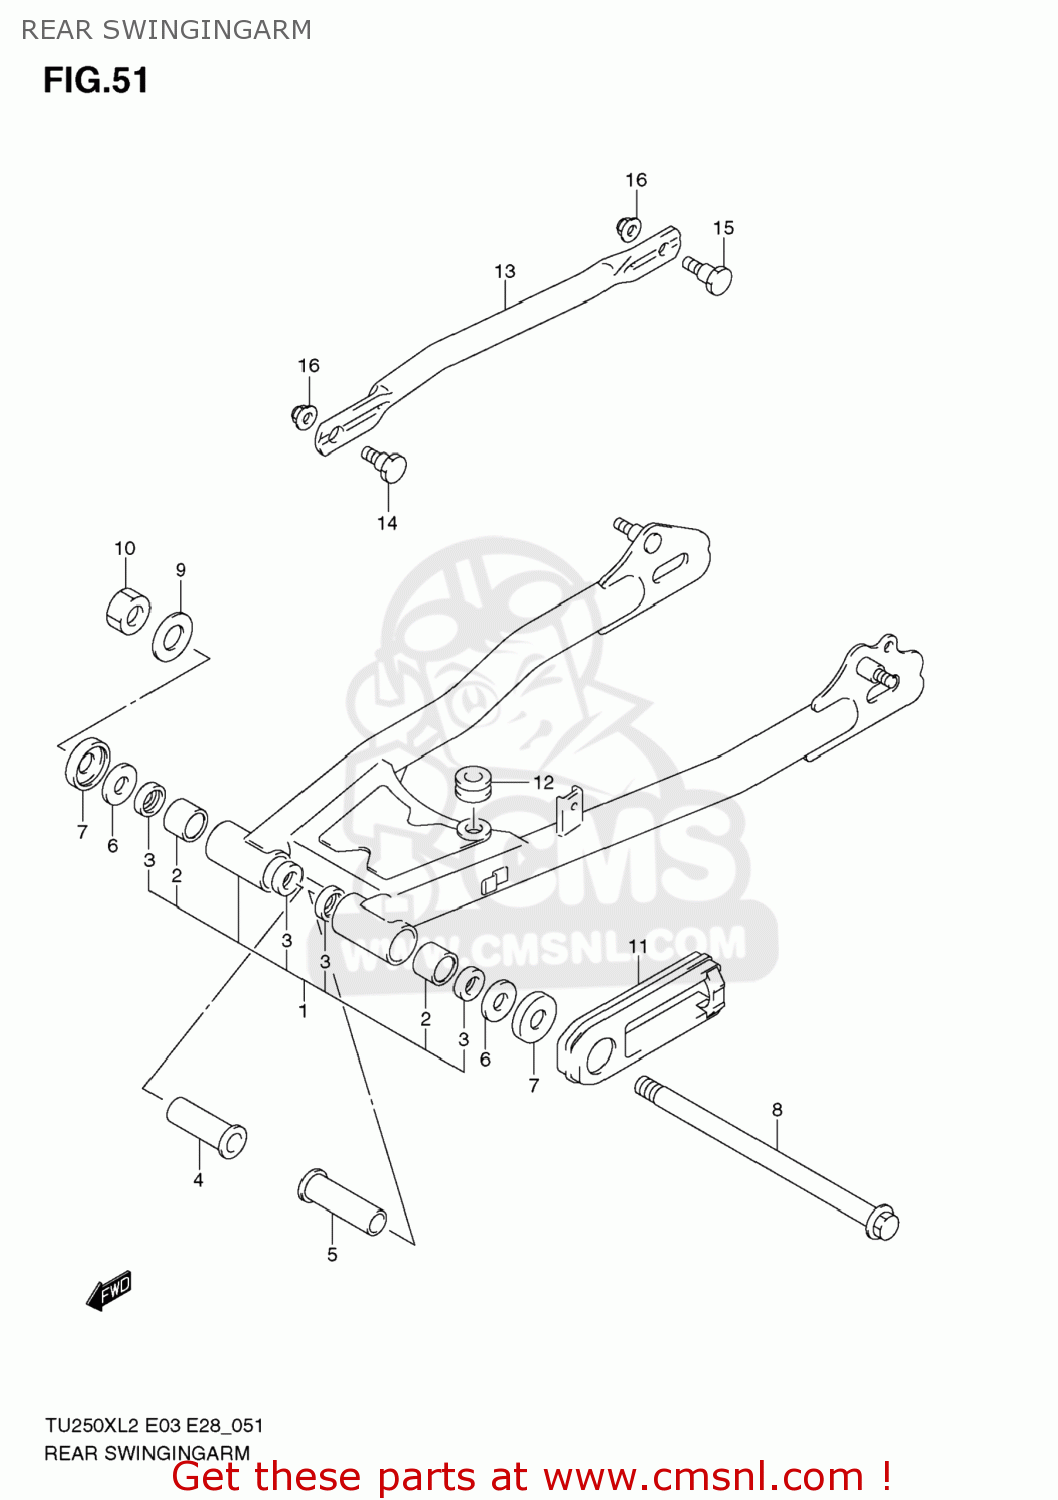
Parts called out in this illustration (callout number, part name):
1	SWINGINGARM ASSY,RR
2	BUSHING,RR SWGARM PIVOT
3	SEAL,OIL(20X27X5)
4	SPACER,RR SWGARM PIVOT,R
5	SPACER,RR SWGARM PIVOT,L
6	WASHER
7	COVER,RR SWINGINGARM PIVOT
8	SHAFT,RR SWINGINGARM PIVOT
9	WASHER
10	NUT
11	BUFFER,CHAIN TOUCH DEFENSE
12	CUSHION
13	TORQUELINK,RR
14	BOLT(8X21)
15	BOLT(8X24)
16	NUT
